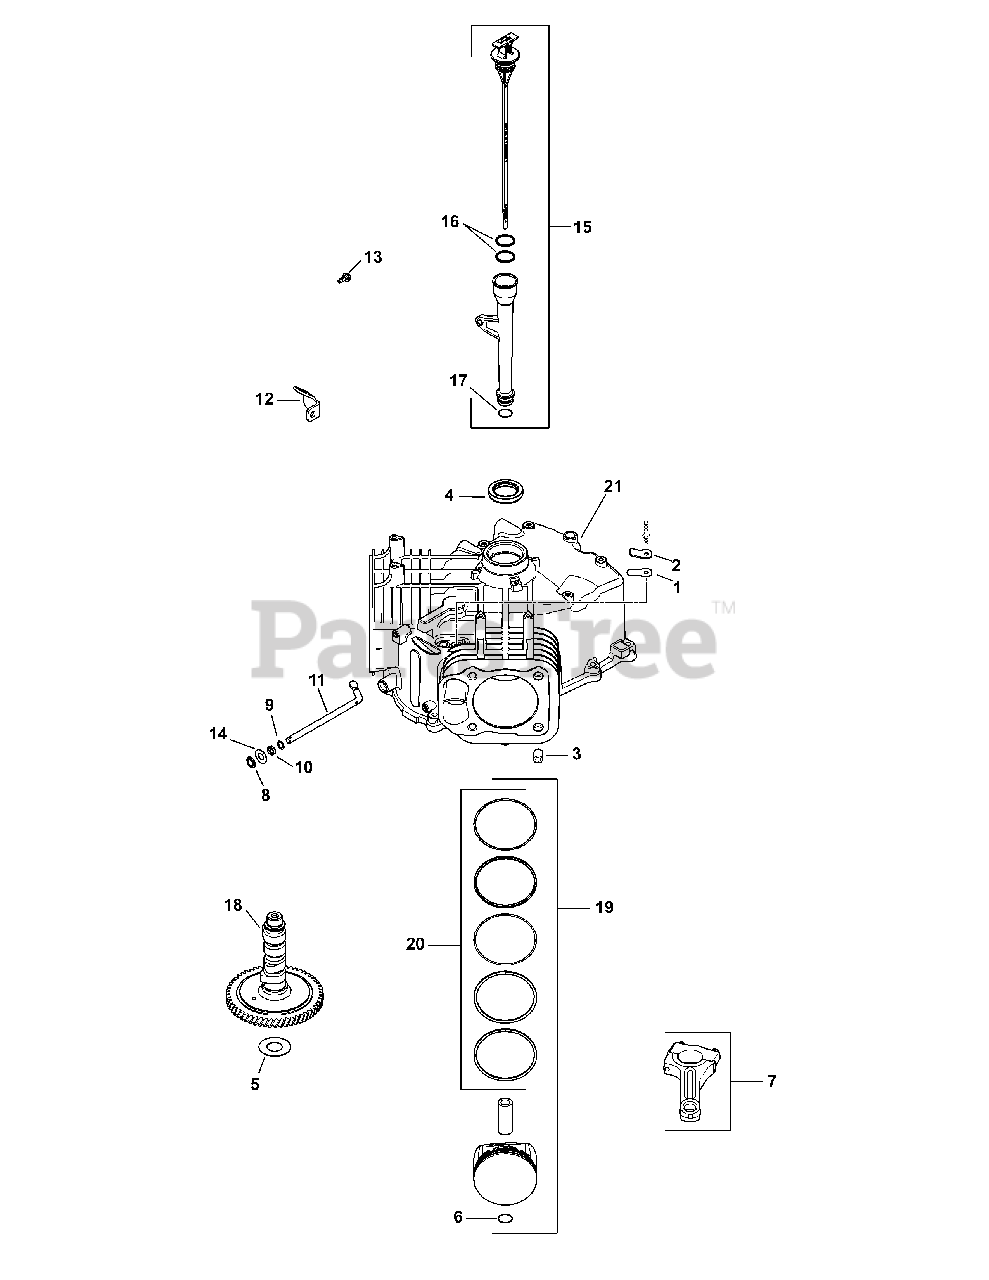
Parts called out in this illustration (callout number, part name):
1	Breather Reed
2	Breather Reed Retainer
4	Oil Seal, 1.78 x 1.26
5	Camshaft Shim, .028 (White)
5	Camshaft Shim, .03 (Blue)
5	Camshaft Shim, .032 (Red)
5	Camshaft Shim, .034 (Yellow)
5	Camshaft Shim, .036 (Green)
5	Camshaft Shim, .038 (Gray)
5	Camshaft Shim, .04 (Black)
6	Piston Pin Retainer
7	Connecting Rod (STD)
8	Ring Retainer
9	Flat Washer, 11/32
10	Governor Cross Shaft Seal
11	Governor Cross Shaft
12	Oil Fill Tube Bracket
13	Flange Screw, M5 x .8 x 13
14	Flat Washer, 9mm
15	Dipstick & Tube Kit
17	Lower Oil Fill Tube O-Ring
18	Camshaft Assembly
19	Piston Kit w/ Ring
19	Piston Kit w/ Ring (0.25) 83mm
19	Piston Kit w/ Ring (0.08) 83mm
20	Ring Set, Piston STD
20	Ring Set, Piston (.08)
20	Ring Set, Piston (.25)
21	Crankcase (Use Short Block)
